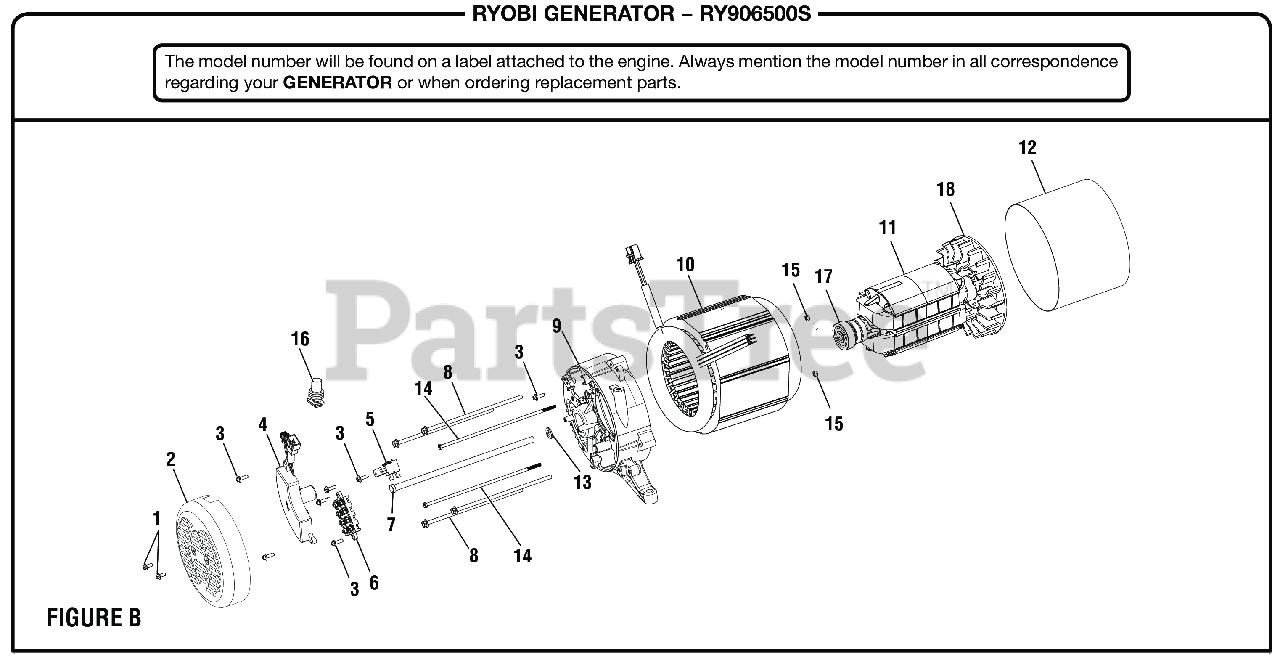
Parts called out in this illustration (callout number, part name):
1	Bolt (M5 x 12 mm, Hex Flange Hd.)
2	Engine Cover
3	Bolt (M5 x 16 mm, Hex Flange Hd.)
4	Automatic Voltage Regulator
5	Brush Assembly Kit
6	Terminal Block Assembly
7	Rotor Bolt (M10 x 272 mm, Hex Hd.)
8	Bolt (M6 x 187 mm, Flange Hex Hd.)
9	Bearing Support
12	Stator Band (139 mm)
13	Washer (ID8.4 x OD25.1 x 3t)
14	Bolt (M6 x 224 mm, Hex Hd.)
15	Hex Nut (M5)
16	Rubber Sleeve
17	Ball Bearing (190 mm)
